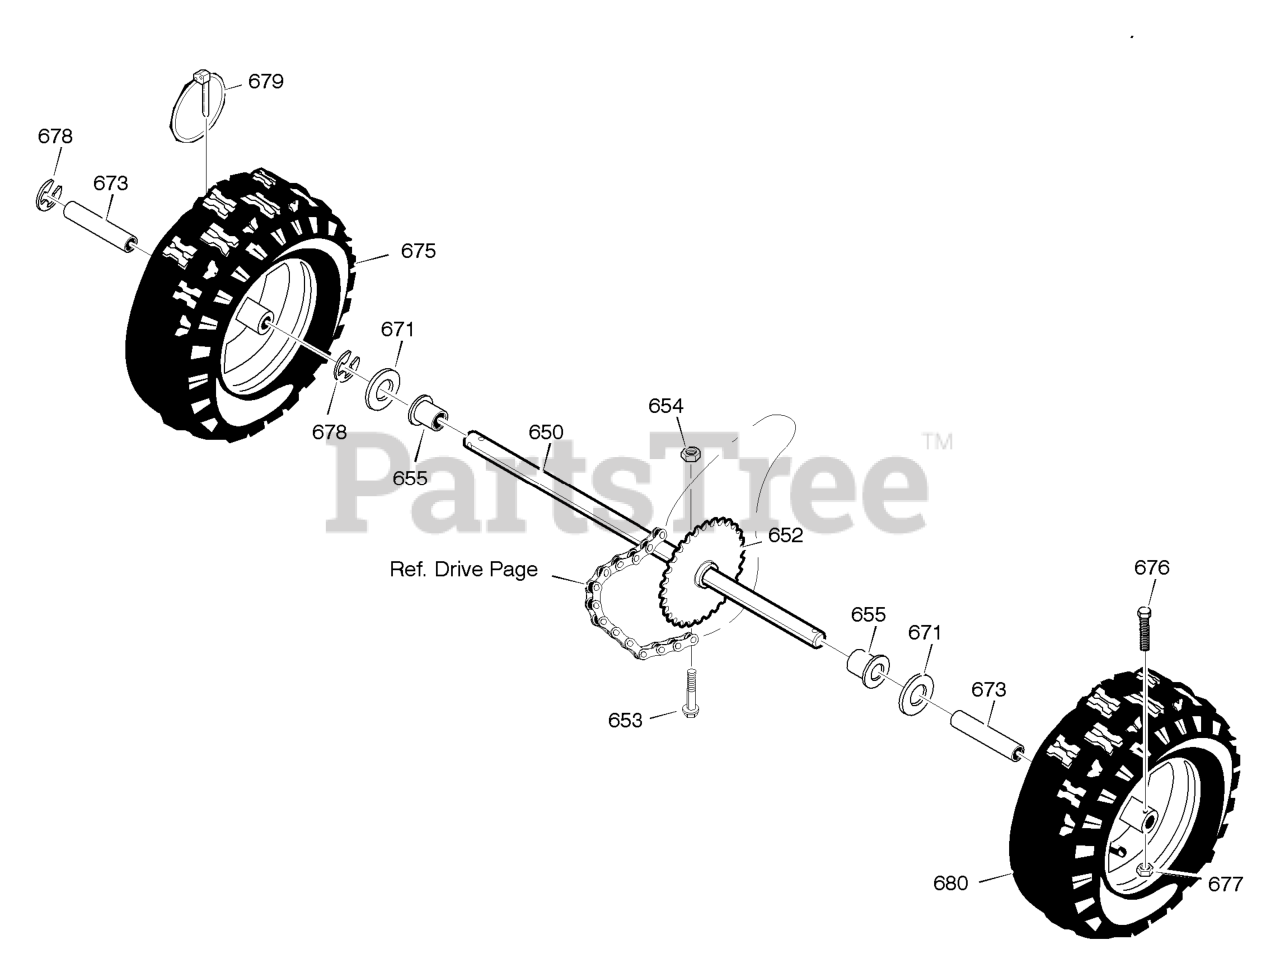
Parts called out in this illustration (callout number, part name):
650	SHAFT, AXLE
652	SPRKT & HUB
653	SCREW, 1/4-20 x 1.75
654	NUT, 1/4-20 HEX NYLOCK
655	BEARING, AXLE
671	WASHER, FLAT
673	BUSHING, WHEEL
675	TIRE & RIM, RIGHT
676	SCREW, 1/4-20X1.75 HH
677	NUT, 1/4-20 HEX NYLOCK
678	RING, RET
679	PIN, KLIK .25 X 1.38 DIA
680	TIRE & RIM, LEFT
